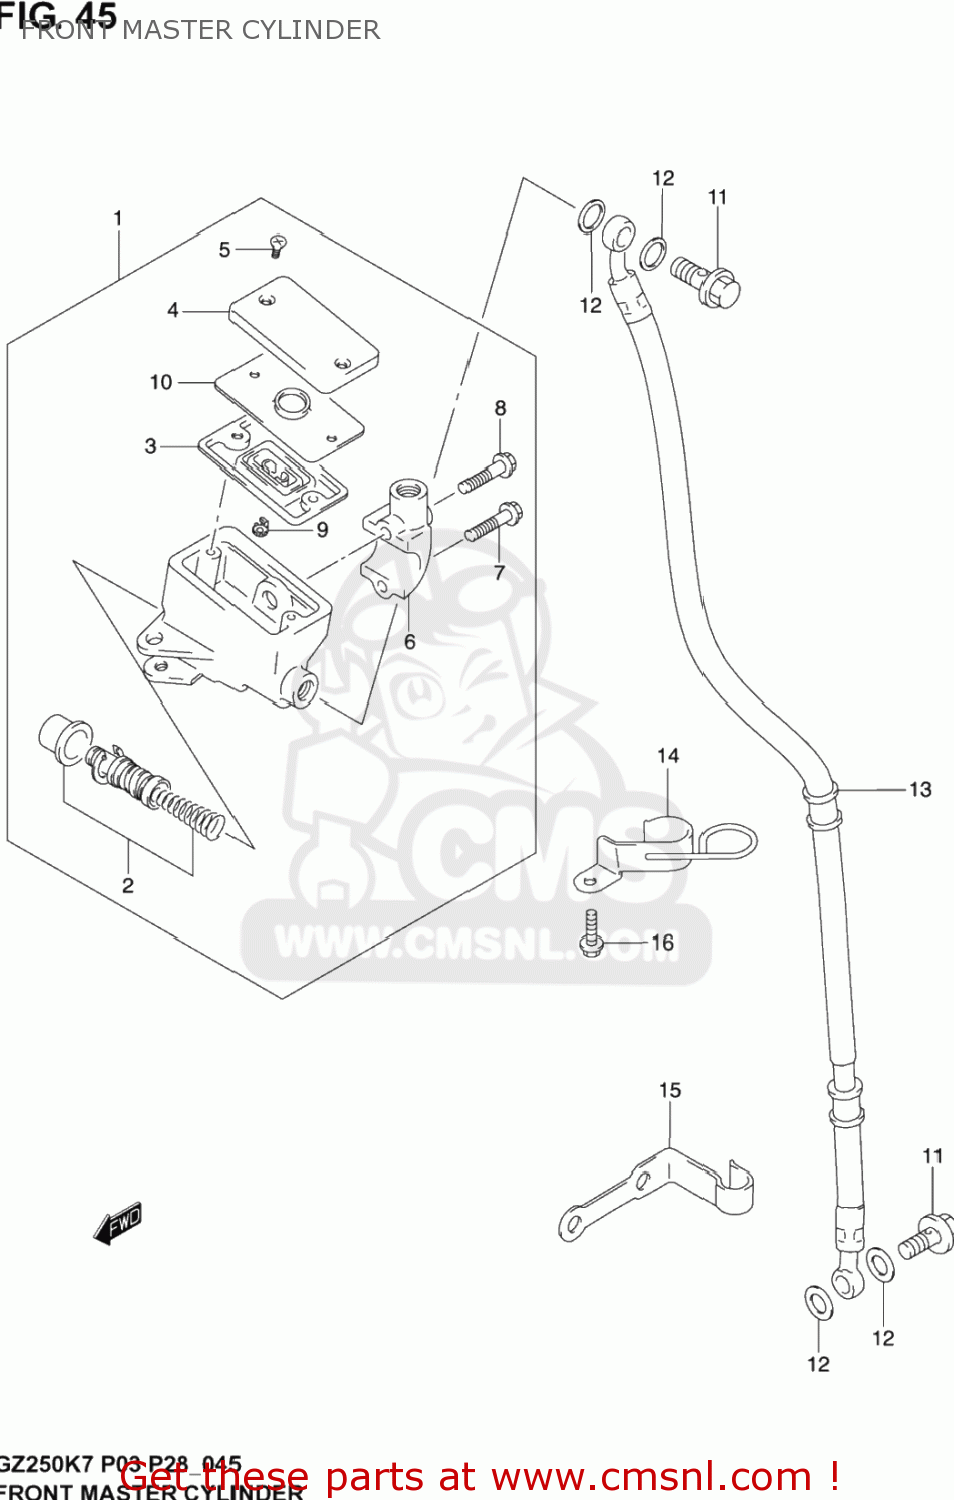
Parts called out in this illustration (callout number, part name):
1	CYLINDER ASSY
2	PISTON/CUP SET
3	DIAPHRAGM
4	CAP
5	SCREW
6	HOLDER
7	BOLT
8	BOLT UPPER
9	PROTECTOR
10	PLATE
11	BOLT UNION
12	WASHER(10X15X1.5)
13	HOSE, FRONT BRAKE
14	CLAMP,FR BRAKE HOSE
15	CLAMP,BRAKE HOSE
16	BOLT
